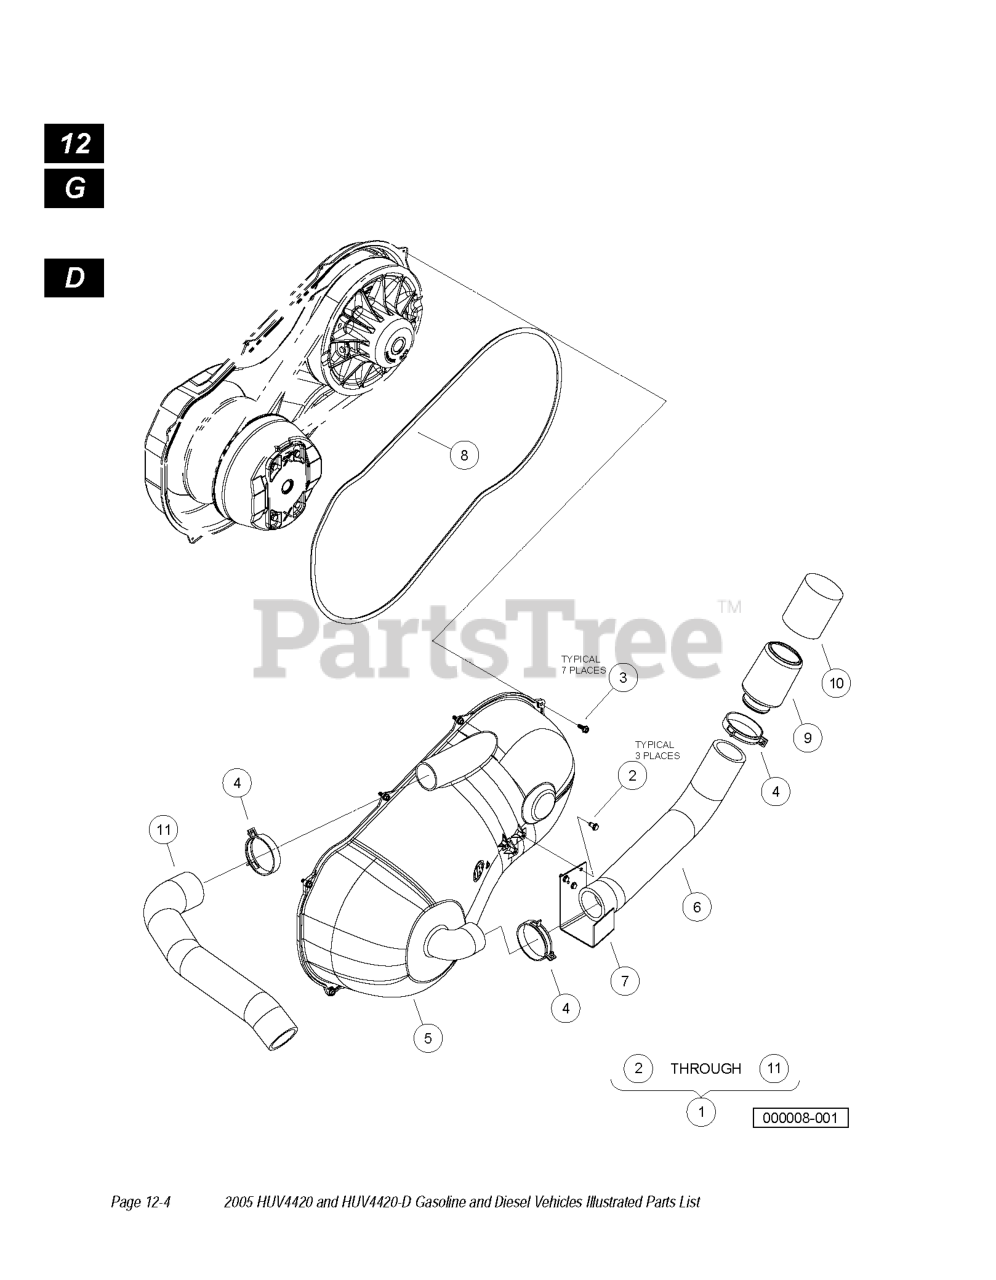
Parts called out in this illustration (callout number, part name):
1	Kit, Sealed CVT Cover
2	SCREW, 1/4-15 X .50 HI-LO HEX
3	SCREW, M6 X 16 TT HX FL HD
4	CLAMP, HOSE, CTB 64MM
5	COVER, CVT OUTER
6	HOSE, INLET, COVER, CVT
7	BRACKET, INLET, COVER, CVT
8	GASKET, COVER, CVT
9	CAP, INLET COVER, CVT
10	FILTER, INLET, COVER, CVT
11	HOSE, OUTLET, CVT
